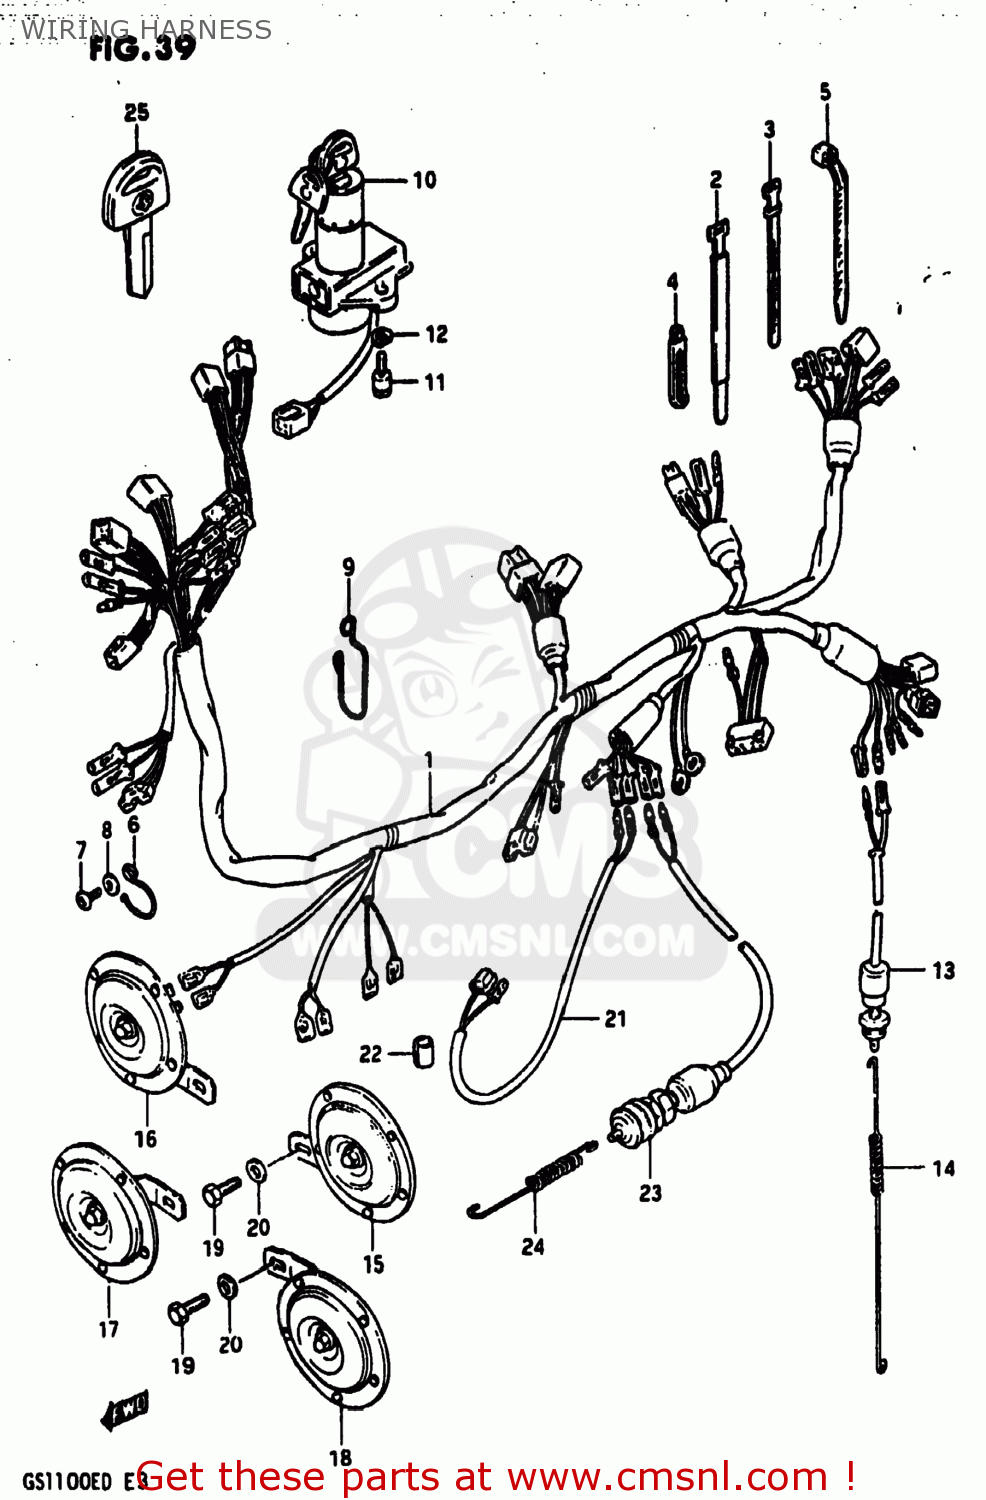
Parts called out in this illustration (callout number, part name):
1	HARNESS,WIRING
2	CLAMP
3	CLAMP(L:120)
4	CLAMP
5	CLAMP(L:95)
6	GUIDE,WIRING HARNESS
7	SCREW 6X12
8	WASHER
9	BOOT,WIRING HARNESS
10	SWITCH ASSY,IGNITION
11	BOLT
12	LOCK WASHER
13	SWITCH ASSEMBLY,STOP LAMP
14	SPRING
15	HORN ASSEMBLY,LOW PITCH
16	HORN ASSEMBLY,HIGH PITCH
17	HORN ASSEMBLY,LOW PITCH
18	HORN ASSEMBLY,HIGH PITCH
19	BOLT 8X12
20	WASHER
21	WIRE
22	CLIP
23	SWITCH ASSEMBLY,SIDE STAND
24	SPRING
25	KEY,BLANK
